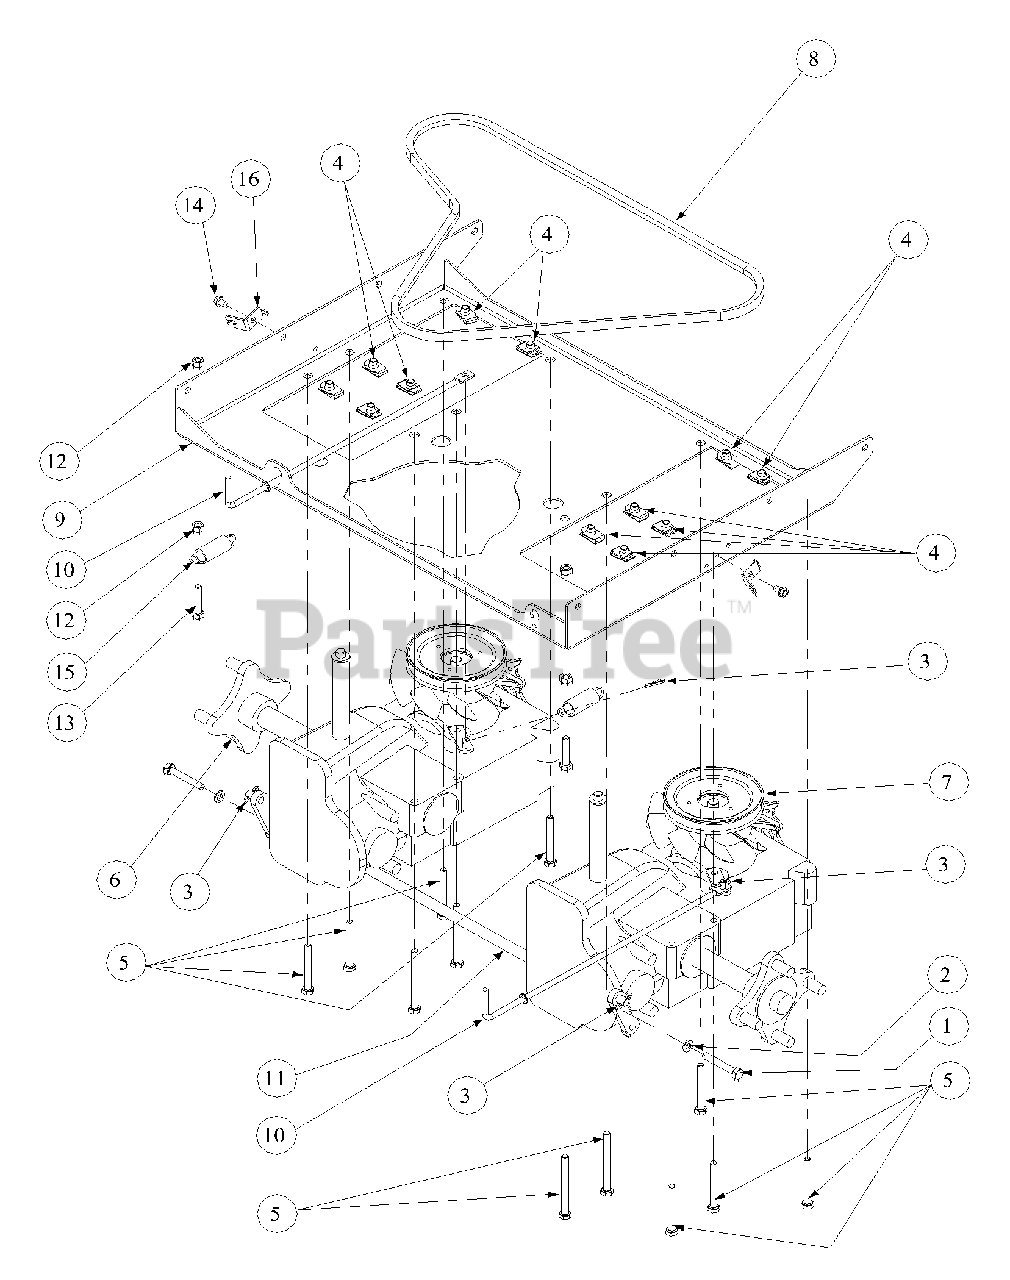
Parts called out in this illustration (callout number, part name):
1	Hex Cap Screw, 5/16-18 x 2.0
2	Flat Washer, .320 ID x .591 OD
3	Cotter Pin, .072 x 1.12 Lg
4	U-Nut, 5/16-18
5	Hex Cap Screw, 5/16-18 x 2.5
6	IZT Transmission, Left Hand
7	IZT Transmission, Right Hand
8	V-Belt, 56.00
9	Transmission Mounting Bracket
10	Pump Rod
11	Transmission Brace Tube
12	Nut, 5/16-18
13	Hex Cap Screw, .438x2.500
14	Screw, 1/4-20 x 1/2
15	Extension Spring, .438 OD X 2.50
16	Brake Cable Mounting Bracket
